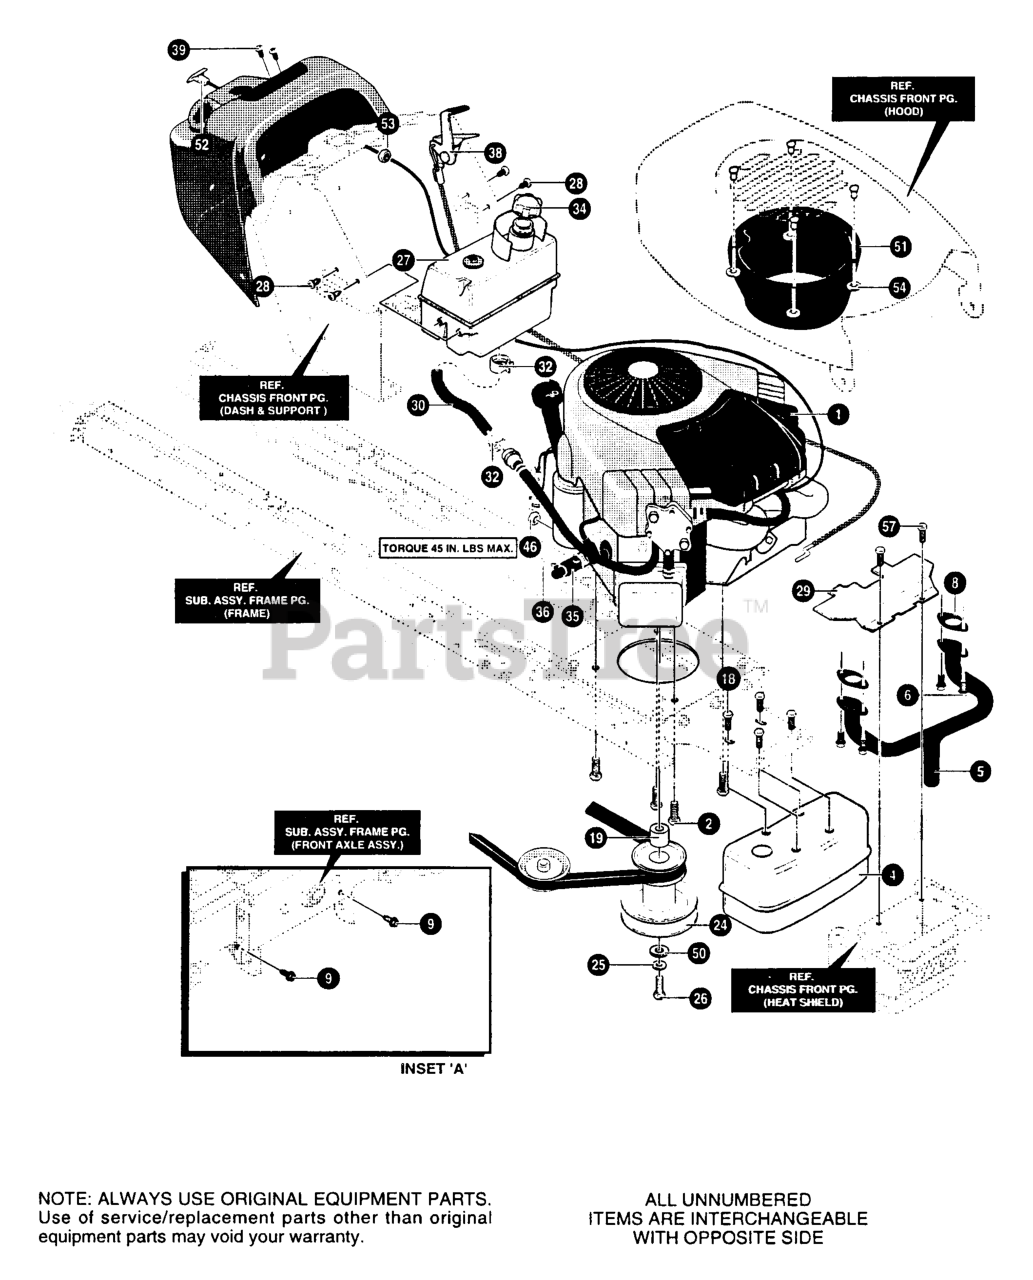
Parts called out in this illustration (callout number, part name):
1	ENGINE 17HP INTEK V-TWIN
2	SCREW, 3/8-16 x 1.25 WAHHTAP
4	MUFFLER, TWIN-CYLINDER
5	TUBE EXHAUST
6	SCREW (B/S #94755)
8	EXHAUST GASKET B/S-273485
9	SCREW, 5/16-18 x 0.75 HHWATAP
18	SCREW, 1/4-20X.63 HHWATAP
19	SPACER, SLEEVE
24	PULLEY, STACK ASSY
25	WASHER, REGSPTLK
26	SCREW 7/16-20X HHC
27	TANK, FUEL W/SENSOR 2.8 GAL
28	SCREW,15TPIX PANHTAP
29	HEAT SHIELD
30	TUBING,.25X.50
32	CLAMP, HOSE SCREW TYPE
34	CAP, FUEL
35	OIL DRAIN VALVE ASSEMBLY
36	CAP, OIL DRAIN VALVE ASSY
38	THROTTLE CONTROL
39	SCREW, #8-16X.50 TRCRTAPAB
46	NUT, 1/4-20 REGHXJAM
50	FLATWASHER.480X1.00X.25
51	PLENUM
52	CHOKE CONTROL
53	NUT, 3/8-16 HWDFL WHIZ-LOCK
54	PUSHNUT
57	SCREW, 1/4-20X.75WAHHTAP
